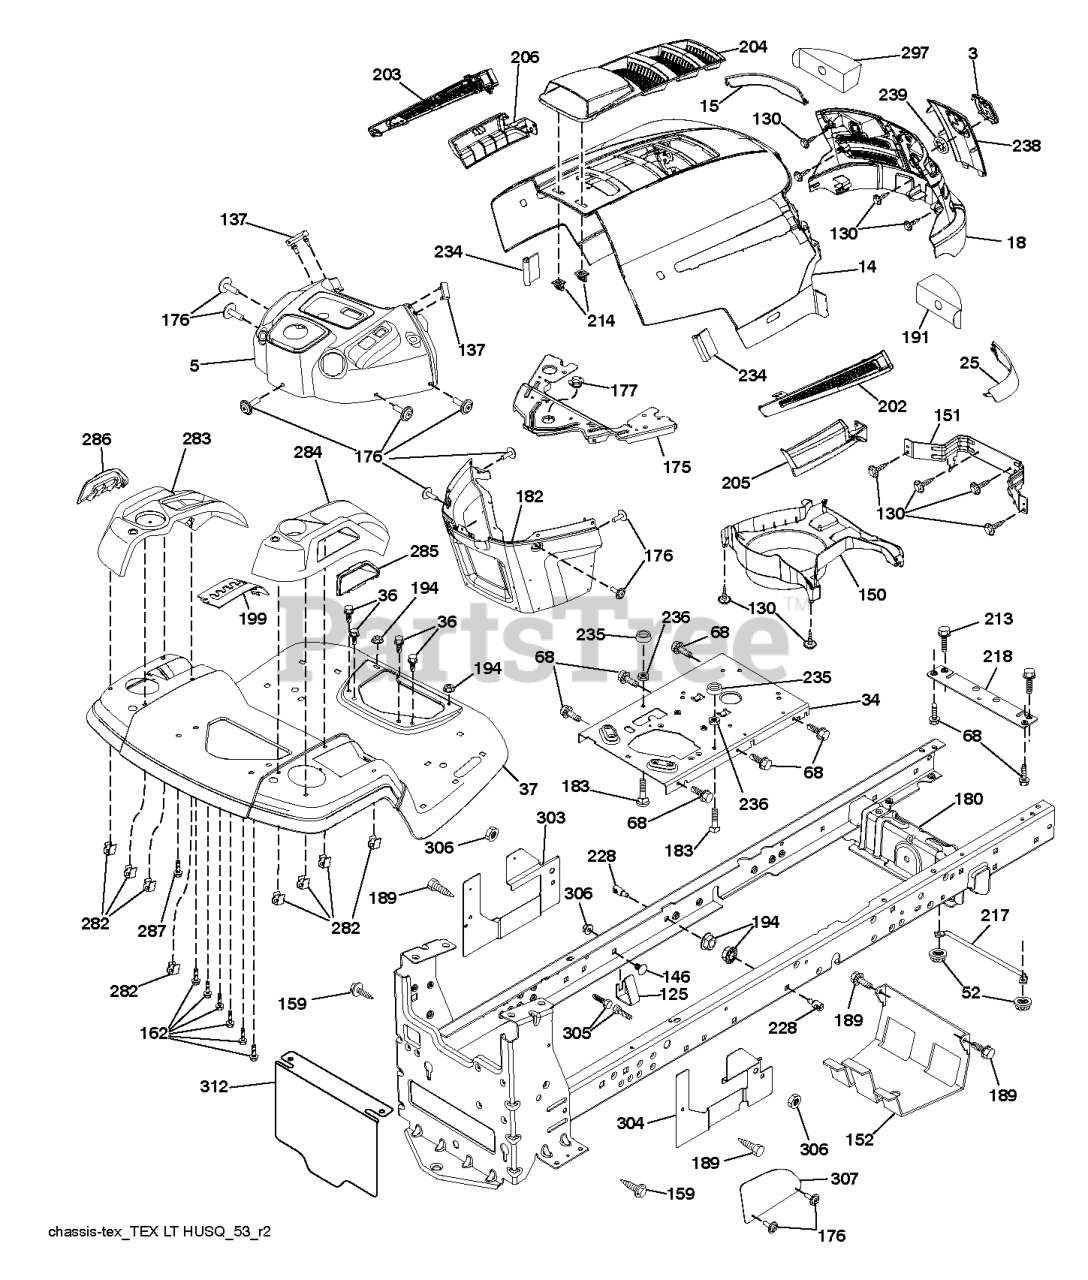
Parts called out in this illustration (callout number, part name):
3	LOGO.HUSQ.GT.LT.CROWN.H
14	HOOD.HUSQVARNA.LT.ORANGE
15	LENS.HUSQVARNA LT.RH
18	GRILLE.SVC.HUSQVARNA.GREY
25	LENS.HUSQVARNA LT.RH
34	PLATE.ENGINE.WELDED.CHASSIS
36	SCREW 5/16"
37	FENDER.TLT.FS.W/CUPHLD.ORANGE
52	LOCKNUT
68	Screw 5/16-18 x 1/2 Hex, Self Tapping 5/16-18 x 1/2
125	CLIP.FUEL.LINE
130	SCREW.#10 X 0.750.BOS
137	BUMPER DASH
146	BOLT.RDHD.SHT.SQNK.3/8-16X5/8
151	BRACKET PIVOT
152	SHIELD.BROWNING.W/TEX
159	SCREW, 3/8-16X3/4
162	SCREW.HI-LO.CONSOLE
175	CROSSMEMBER
176	SCREW.#10-24X5/8.RN.QU
177	BUSHING STEERING
180	CHASSIS
182	DASH.LOWER.PREDATOR LT
183	BOLT.5/16-18X1-1/4 FULL THD
189	SCREW
191	INSERT.REFLECTIVE.RH.
194	NUT LOCK HEX FLANGE 5/16-18
199	PLATE.DECK.LIFT.HUSQ.LT
202	VENT.SIDE.HUSQVARNA.LT.RT
203	VENT.SIDE.HUSQVARNA.LT.LFT
204	SUBASM.TOP.VENT.HUSQ.LT
205	SKIRT.SIDE.HUSQVARNA.LT.RT
206	SKIRT.SIDE.HUSQVARNA.LT.LEFT
213	BOLT
214	CLIP.RETAINER.TINNER.
217	ROD.PIVOT.HOOD
218	X-PIECE.HOOD.STOP.NON/
228	STUD.FASTNER.W/ANTI-ROTATE
234	BUMPER.HOOD.TEX.HUSQVARNA
235	SPACER FENDER
236	NUT.CENTERLOCK.5/16-
238	TRIM.HUSQ LT.668
282	CLIP.RETAINER.CONSOLE.LT.HUSQ
283	CONSOLE.ASM.LFT.RSF.HUSQ.LT
284	CONCOLE.CNTRL.PDL.HUSQ.LT.498
285	CONSOLE INSERT RH
286	CONSOLE.INSRT.LH.HUSQ.LT.BLACK
287	SCREW 1/4X20
297	INSERT REFLECTIVE
303	SHIELD CHASSIS LEFT
304	SHIELD CHASSIS RIGHT
305	BOLT
306	NUT LOCK FLG 3/8-16 UNC
307	SHIELD UPPER PEDAL
312	SHIELD.PNT.DRAWBAR.FRENCH
